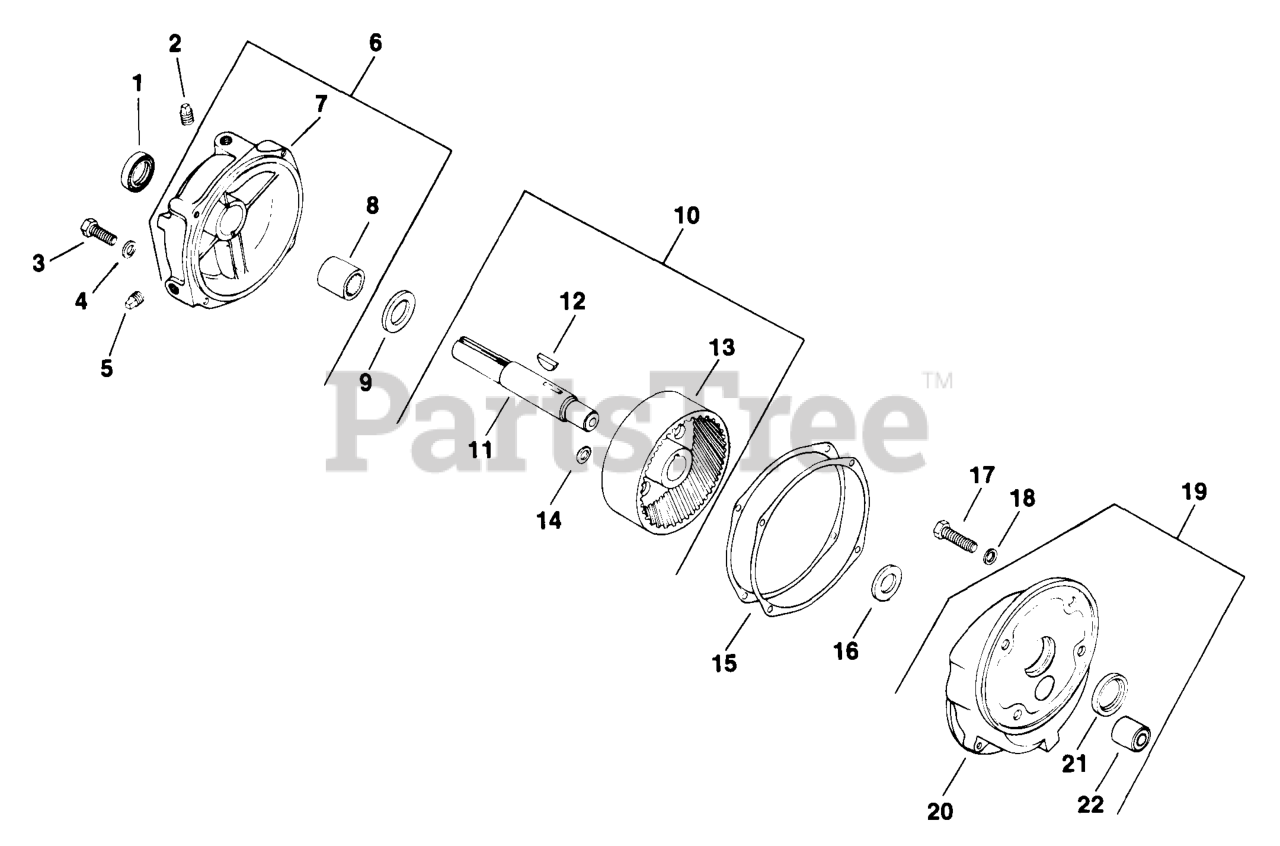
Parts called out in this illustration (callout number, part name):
1	SEAL, REAR OIL
3	SCREW,CAP HD 5/16-18x2"
4	WASHER, SPRING LOCK 5/16"
5	PLUG,PIPE 1/4 NPTF SQUARE HD USE 25 139 53-S
6	COVER - USE 12 081 06
7	COVER - DISCONTINUED
8	BEARING - DISCONTINUED
10	RED GEAR - DISCONTINUED
11	SHAFT - DISCONTINUED
12	KEY, 3/16" X 1"
13	GEAR - (#DSC)
17	SCREW - DISCONTINUED
18	WASHER, SPRING LOCK 3/8"
19	HOUSING - DISCONTINUED
20	HOUSING - (#DSC)
21	SEAL, FRONT OIL
22	BEARING
